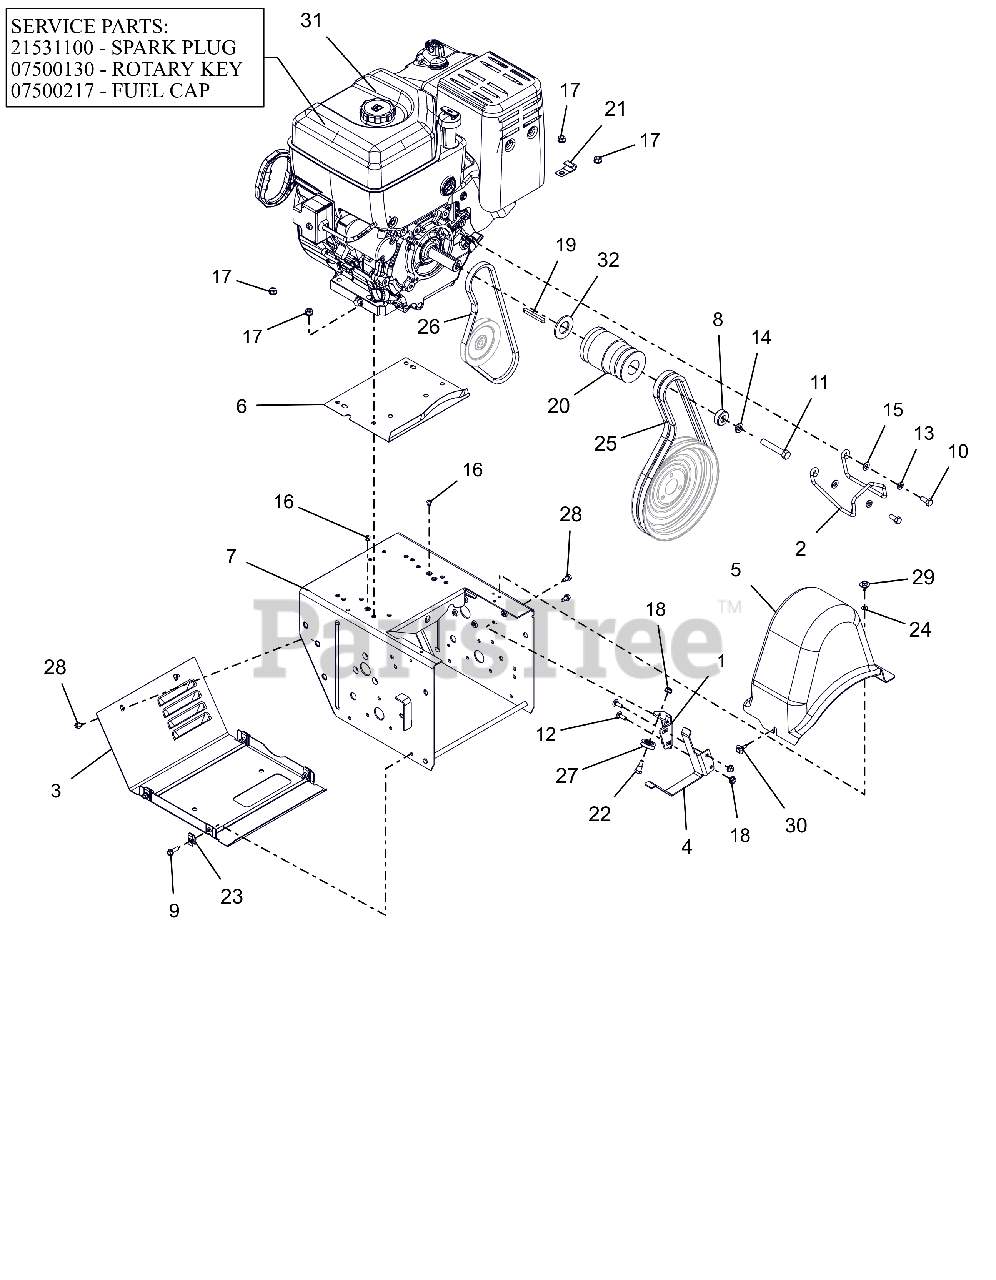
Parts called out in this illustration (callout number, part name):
1	BRACKET, CLUTCH CABLE
2	FINGER, BELT
3	COVER, BOTTOM - VENTILATED
4	FINGER, BELT - FLAT
5	COVER, BELT-LARGE
6	BAFFLE, WATER - LARGE BLOCK
7	FRAME, MAIN - PRO (WELDMENT)
8	BSHG-SPACER .47X1.25X.50
9	BLT, HWH .25-20X.75 G5 ZCC
10	BLT, HEX .31-24X.750 G5 ZCC
11	BLT, HEX .44-20X2.50 G5 ZCC
12	BLT, RHSN .25-20X.750 G5 ZCC
13	WSHR, LK-HVY .312X.097 ZCC
14	WSHR, LK-REG .438X.109 ZCC
15	WSHR,FLT .344X.688X.065 ZCC
16	RVT, POP .1875 ZCC
17	NUT,LK-CTR-FLG .31-18 GF ZCC
18	NUT-LK-TOP-FLG .250-20 GF ZCC
19	KEY, SQ .248/.246 X 2.25
20	SHEAVE, COMBO HYDRO TRACK 4L
21	J-CLAMP
22	BOLT, SHLDR -.375 X .375 X .25-20
23	NUT-RTNR .25-20X.56
24	NUT-PUSH .25X.50 O.D.
25	V-BELT, HA-RAW EDGE (SET)
26	V-BELT, 4L-WRAPPED
27	PULLEY, CABLE
28	SCR-TAP .25-20X.50 HWH ZCC
29	SCR, TAP .25-20X.50 LG HWH ZCC
30	SCR-TAP .25-20X.5 CAPTIVE
31	ENGINE, BRIGGS PF 2100, 120V
31	PLUG, SPARK 20HP B&S VANGUARD
31	KEY, IGNITION ROTARY B&S
31	CAP, FUEL - BRIGGS & STRATTON
32	WSHR, FLT 1.062X2.000X.134 ZCC
